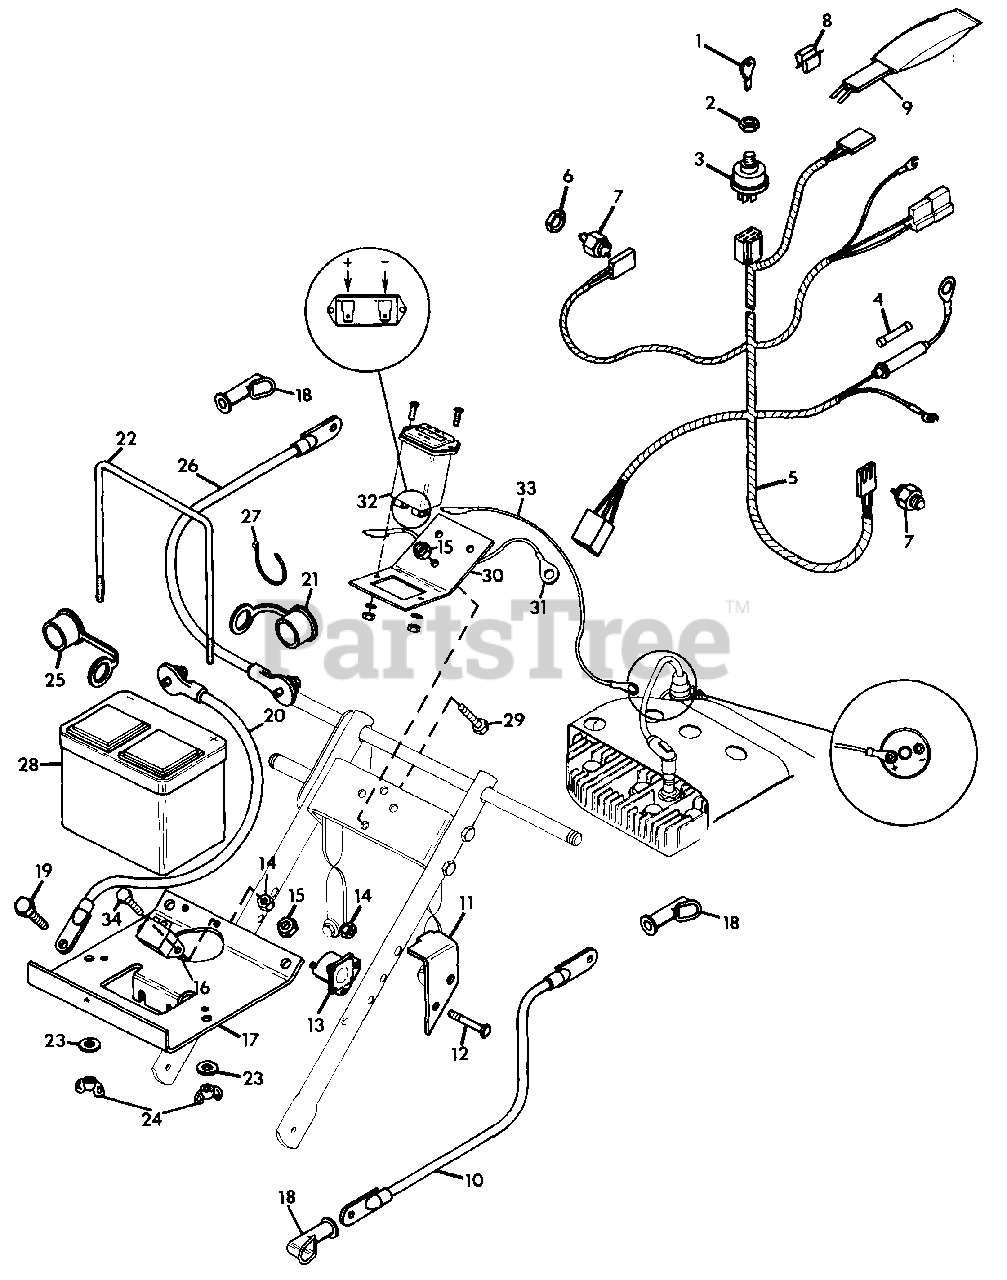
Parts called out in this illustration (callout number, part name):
1	KEY, IGNITION
2	NUT, JAM 9/16-24
3	SWITCH, IGNITION
4	FUSE, 30 AMP
5	HARNESS, WIRING
6	NUT, STAMPED
7	SWITCH, INTERLOCK
8	CLIP, WIRE
9	SWITCH, SEAT
10	CABLE
11	BRACKET, PTO
12	BOLT, HEX 1/4-20X2.00
13	SWITCH, MAG
14	NUT, LOCK 1/4-20
15	NUT, LOCK 3/8-16
16	REGULATOR, RECTIFIER
17	BOX, BATTERY
18	BOOT, BATTERY CABLE
19	BOLT, HEX 3/8-16X2.25
20	CABLE, NEGATIVE BATTERY
21	COVER, BATTERY POS.
22	ROD, BATTERY
23	WASHER, FLAT .281X.625X.065
24	NUT, WING 1/4-20
25	COVER, BATTERY NEG.
26	CABLE, POSITIVE BATTERY
27	TIE, CABLE
28	BATTERY, DELCO MAINTENANCE-FREE #101 -REPLACEMENT BATTERY #83-50
29	BOLT, HEX 3/8-16X.875
30	BRACKET, HOURMETER
31	WIRE, INSTRUMENT PANEL
32	HOURMETER
33	WIRE, HOURMETER
34	BOLT, HEX 1/4-20X1.00
